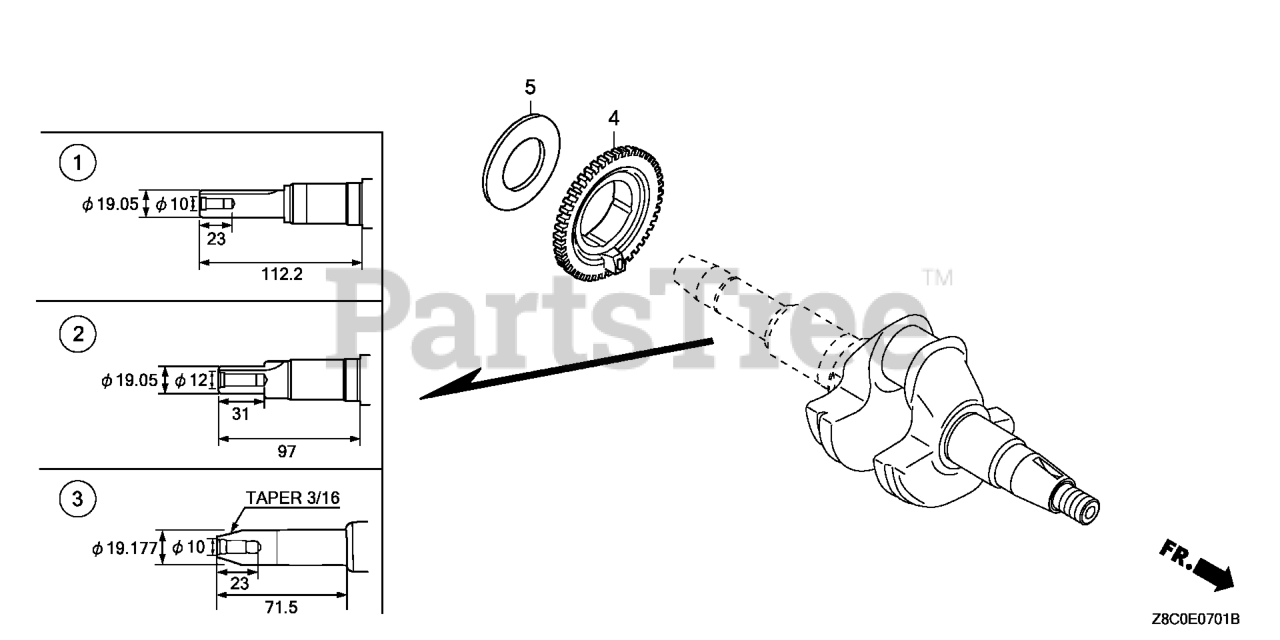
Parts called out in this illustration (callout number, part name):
1	CRANKSHAFT
4	PULLEY, TIMING BELT DRIVE
5	WASHER, THRUST
